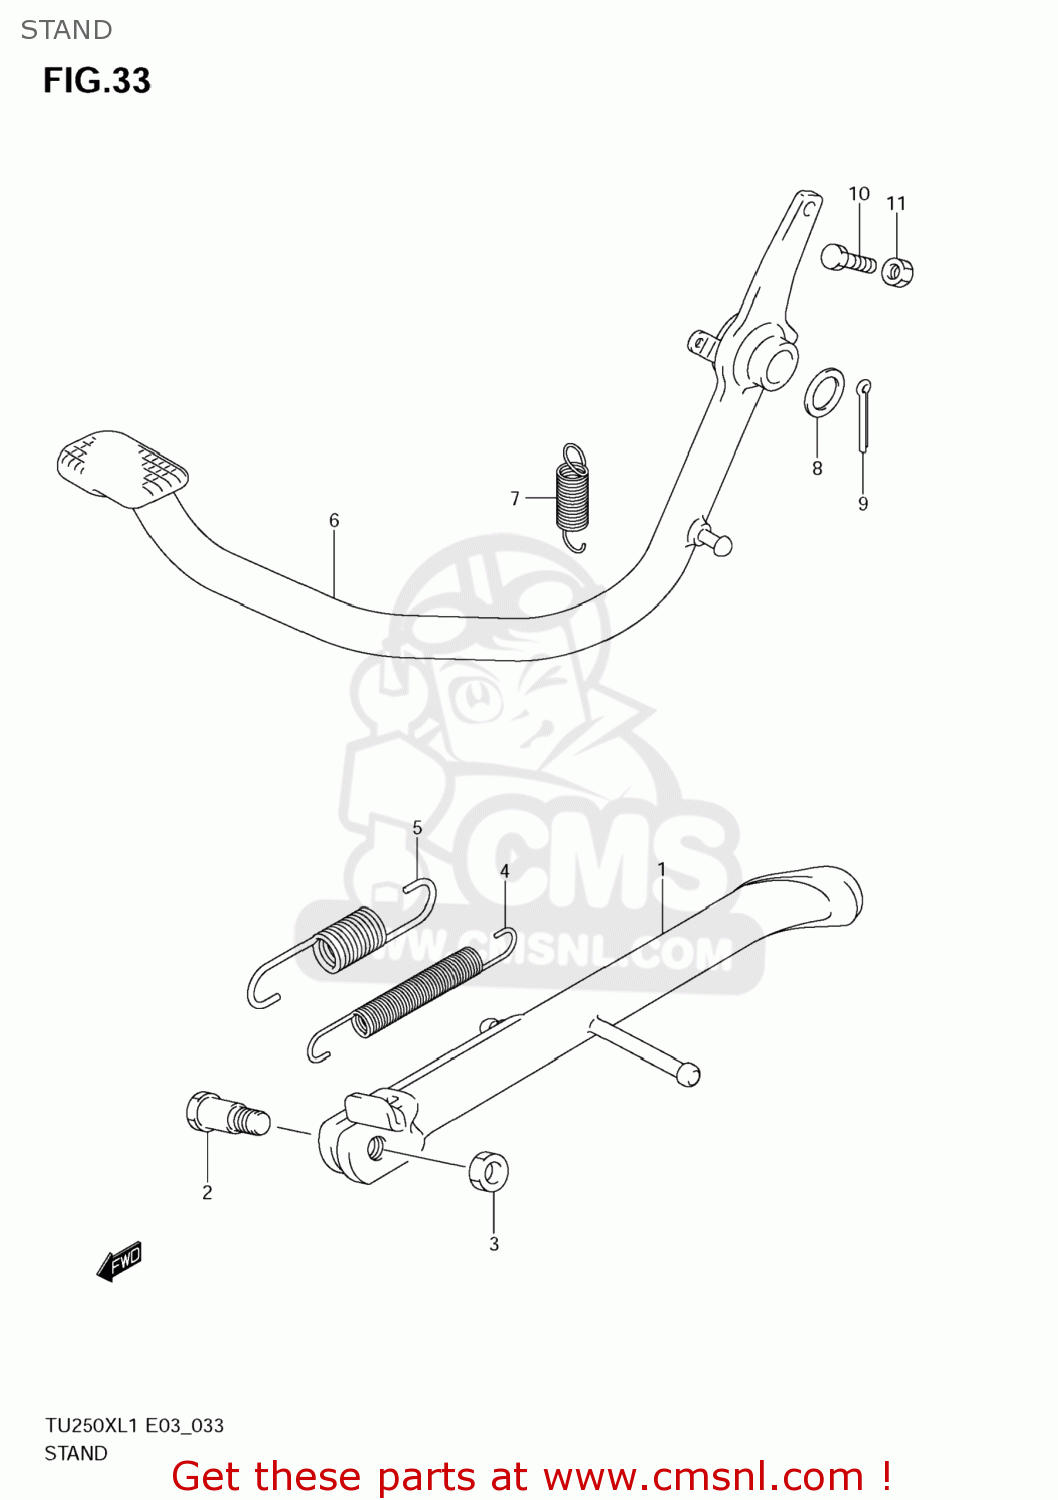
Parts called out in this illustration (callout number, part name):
1	STAND,PROP
2	BOLT(10X38)
3	NUT
4	SPRING
5	SPRING
6	PEDAL,BRAKE
7	SPRING
8	WASHER(15.5X26X2.3)
9	PIN
10	BOLT(6X23)
11	NUT
